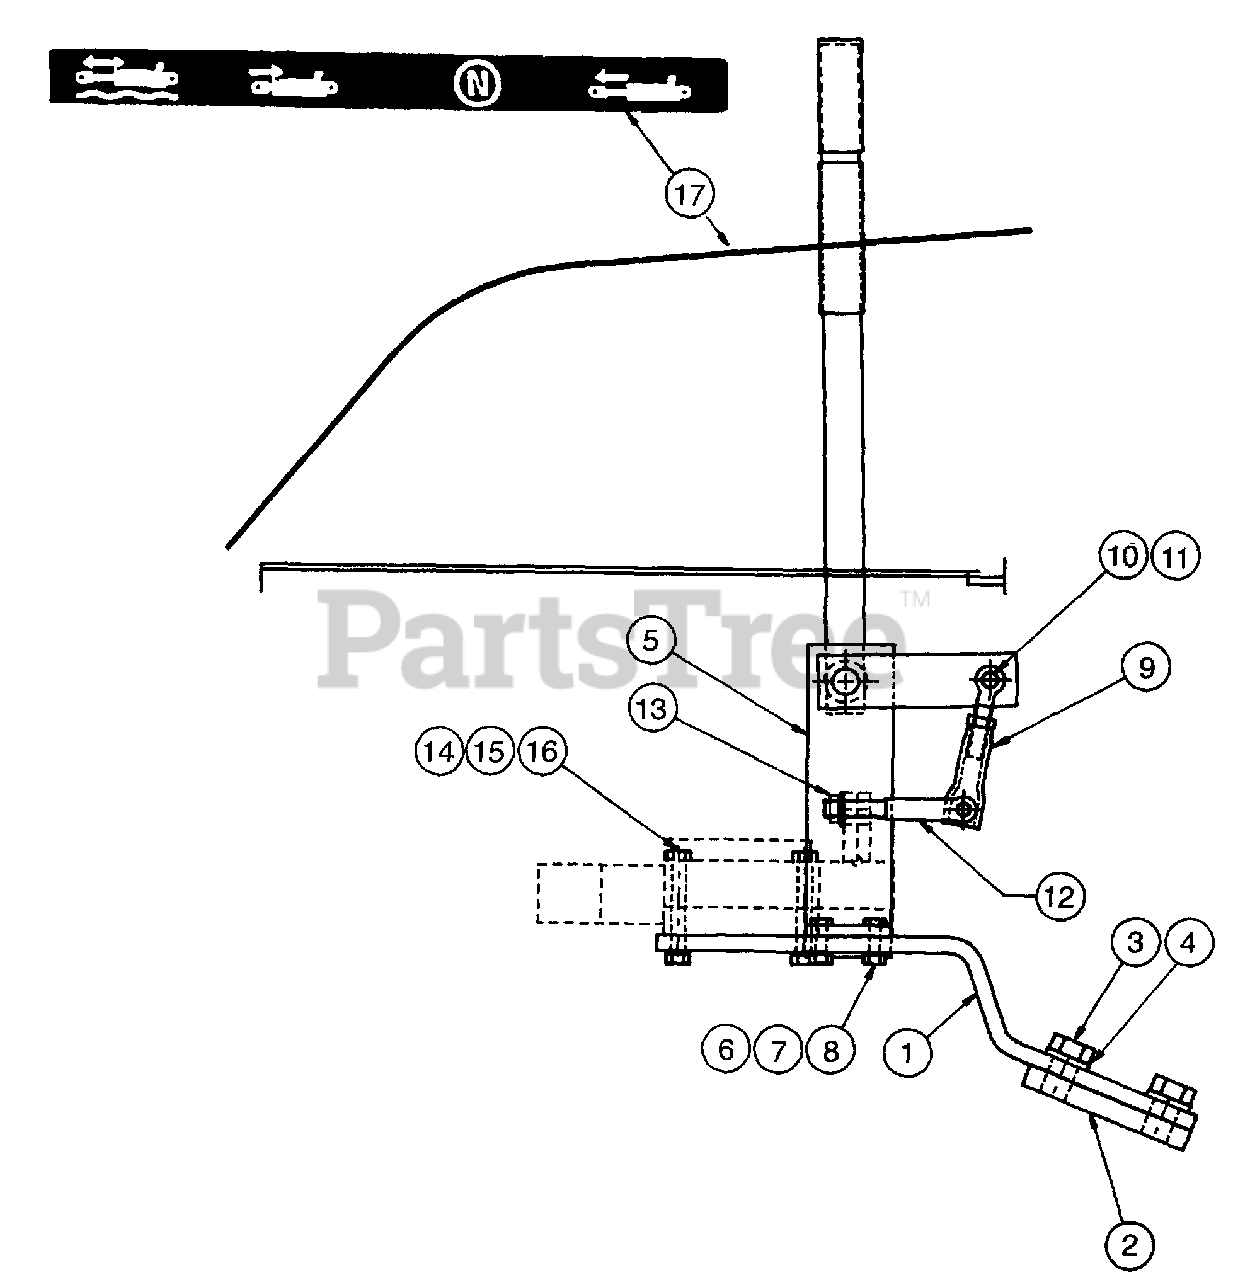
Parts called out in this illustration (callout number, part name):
1	Valve plate assembly
3	Bolt M14-2 x 45mm
4	Lock washer
5	Handle-Stand assembly
6	Bolt 1/4-20 x 1 GR5
7	Nut 1/4-20
8	Lock washer 1/4
9	Free link assembly
10	Flat washer 3/8
11	Cotter pin
12	Valve link
13	Serrated flange nut M10-1.5
14	Bolt 5/16-18 x 2 1/4 GR5
15	5/16 NC Nut
16	Lock washer 5/16
17	Decal
